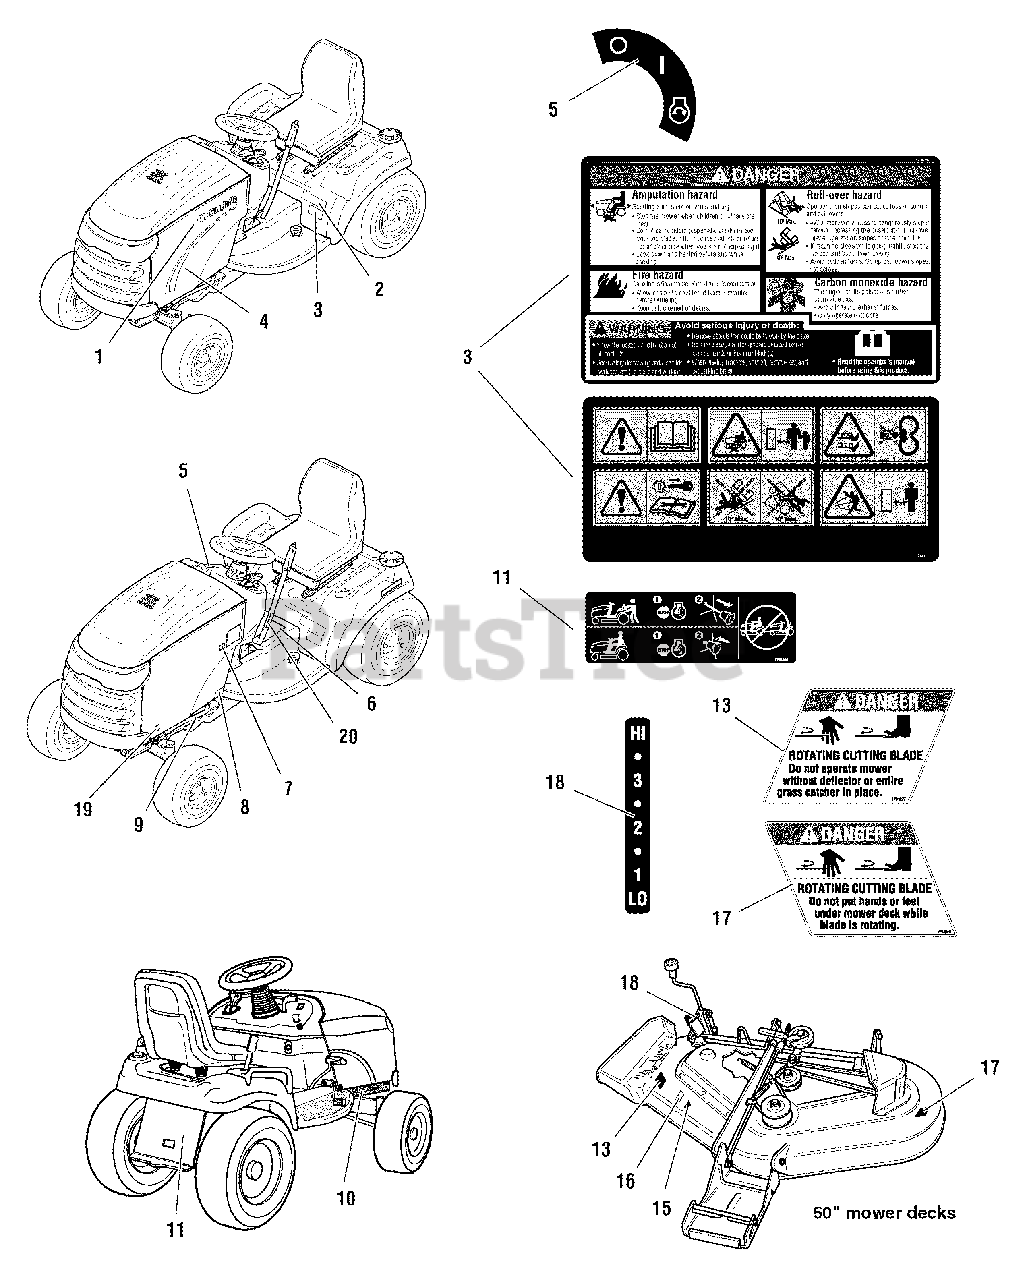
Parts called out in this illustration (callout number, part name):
1	DECAL, Simplicity Silver & Blue w/Icon
2	DECAL, Conquest, Silver & Blue
3	DECAL, 23HP Silver on Clear
4	DECAL, Hood Stripe R.H. SMI Blue & Silver
4	DECAL, Hood Stripe L.H. SMI Blue & Silver
5	DECAL, Ignition Switch Symbols
6	DECAL, Tunnel Cover Danger Slopes, Blades
7	DECAL, Touch Up Paint
8	STICKER, Protection
9	DECAL, I.D. Plate
10	DECAL, Patent
11	DECAL, Transmission Release Valve
13	DECAL, Danger Do Not Operate w/o Deflector
13	DECAL, Danger Rotating Blade
15	DECAL, OPEI Certified
16	DECAL, 50" Silver on Black w/Stripe
17	DECAL, Danger Do Not Put Hand/Feet In Mower
18	DECAL, 1 2 3 4 5 6, Height of Cut White/Black
20	DECAL, Lift
